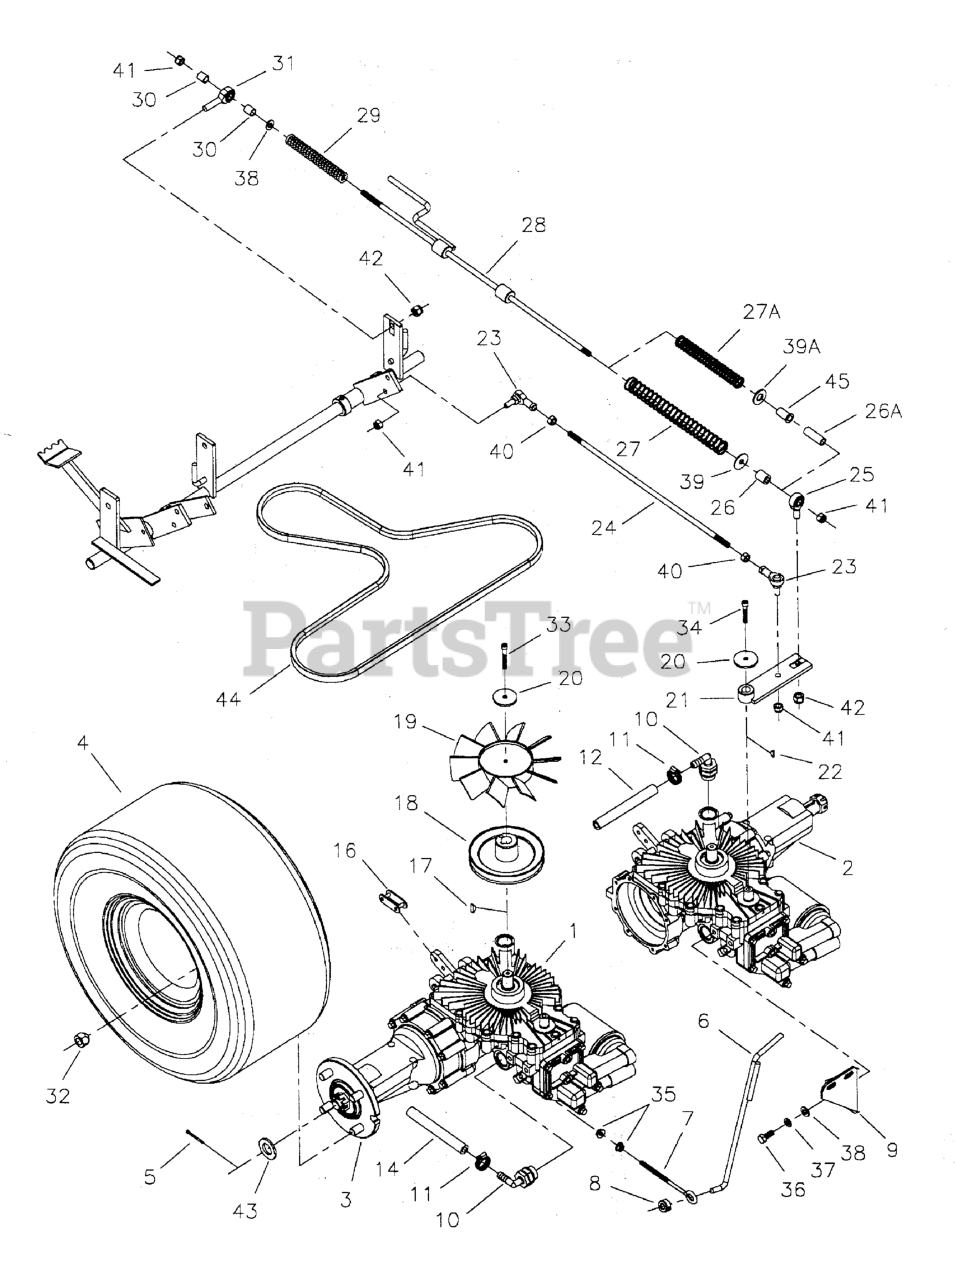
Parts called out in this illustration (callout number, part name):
1	TRANSAXLE, 771-101, RIGHT SIDE
1	FILTER, Transmission Oil
1	NUT, Hex Slotted
1	KEY, Woodruff
2	TRANSAXLE, 771-102, LEFT SIDE
3	HUB, 4-Bolt Tapered
4	TIRE & WHEEL ASSEMBLY, 18 X 8.5 X 8
4	WHEEL & TIRE ASSEMBLY, 18 x 7.50 x 8
5	PIN, COTTER, 1/8 X 1-1/4
6	LEVER, Dump Valve
7	EYEBOLT, 1/4-20 x 4
8	COLLAR, 5/16" Set
9	BRACE, Transmission
10	FITTING, 7/8" O-Ring - 3/8" Hose, 90 Degree
11	CLAMP, #6 HOSE, STAINLESS
12	HOSE, 3/8" PUSH-LOCK, 37.00"
14	HOSE, 3/8" PUSH-LOCK, 35.00"
16	LINK, #A20/50 CONNECTING
17	KEY, Hi-Pro Woodruff
18	PULLEY, Transmission
19	FAN
19	FAN, WHITE
20	WASHER, .265 X 1.50 X .109, YZ
21	ARM, Hydro Stroke
22	KEY, #3 Woodruff
23	BALL JOINT, 5/16-24 RH FEMALE W/STUD, BR
24	ROD, TRANSMISSION REVERSE
25	BALL JOINT
26	BUSHING, Brass
26A	BUSHING, BRASS, 3/8 X 5/8 X1.5
27	SPRING, Compression
27A	SPRING-COMP, .600ID X 5.50LG X .080WR
28	ROD, Stroke Arm
29	SPRING-COMP, .435ID X 4.75LG X .137WR
30	SPACER, .38 X .50 X .562
31	BALL JOINT, 3/8-24 Male
32	NUT, 1/2-20, FOR WHEEL BOLT SILVER
33	Bolt, 1/4-20 x 3/4" Allen Head wi Patch
34	Bolt, 1/4-20 x 1/2," Allen Head wi Patch
35	NUT, 1/4-20 HEX SERR. FLANGE
36	BOLT, 5/16-18 X 3/4 GD5
37	WASHER, 5/16 LOCK CZ
38	WASHER, 5/16" SAE
39	WASHER, 5/16" Fender
39A	WASHER, 1/2 SAE
40	NUT, Hex, 5/16-24
41	NUT, 5/16-24 HEX NYLON LOCK
42	NUT, 3/8-24 Hex Nylon Lock
43	WASHER, 3/4 SAE
44	BELT, SPA-SEC, 66.26" EL, ARAMID, WRAPED
45	BUSHING, Plastic Flange
